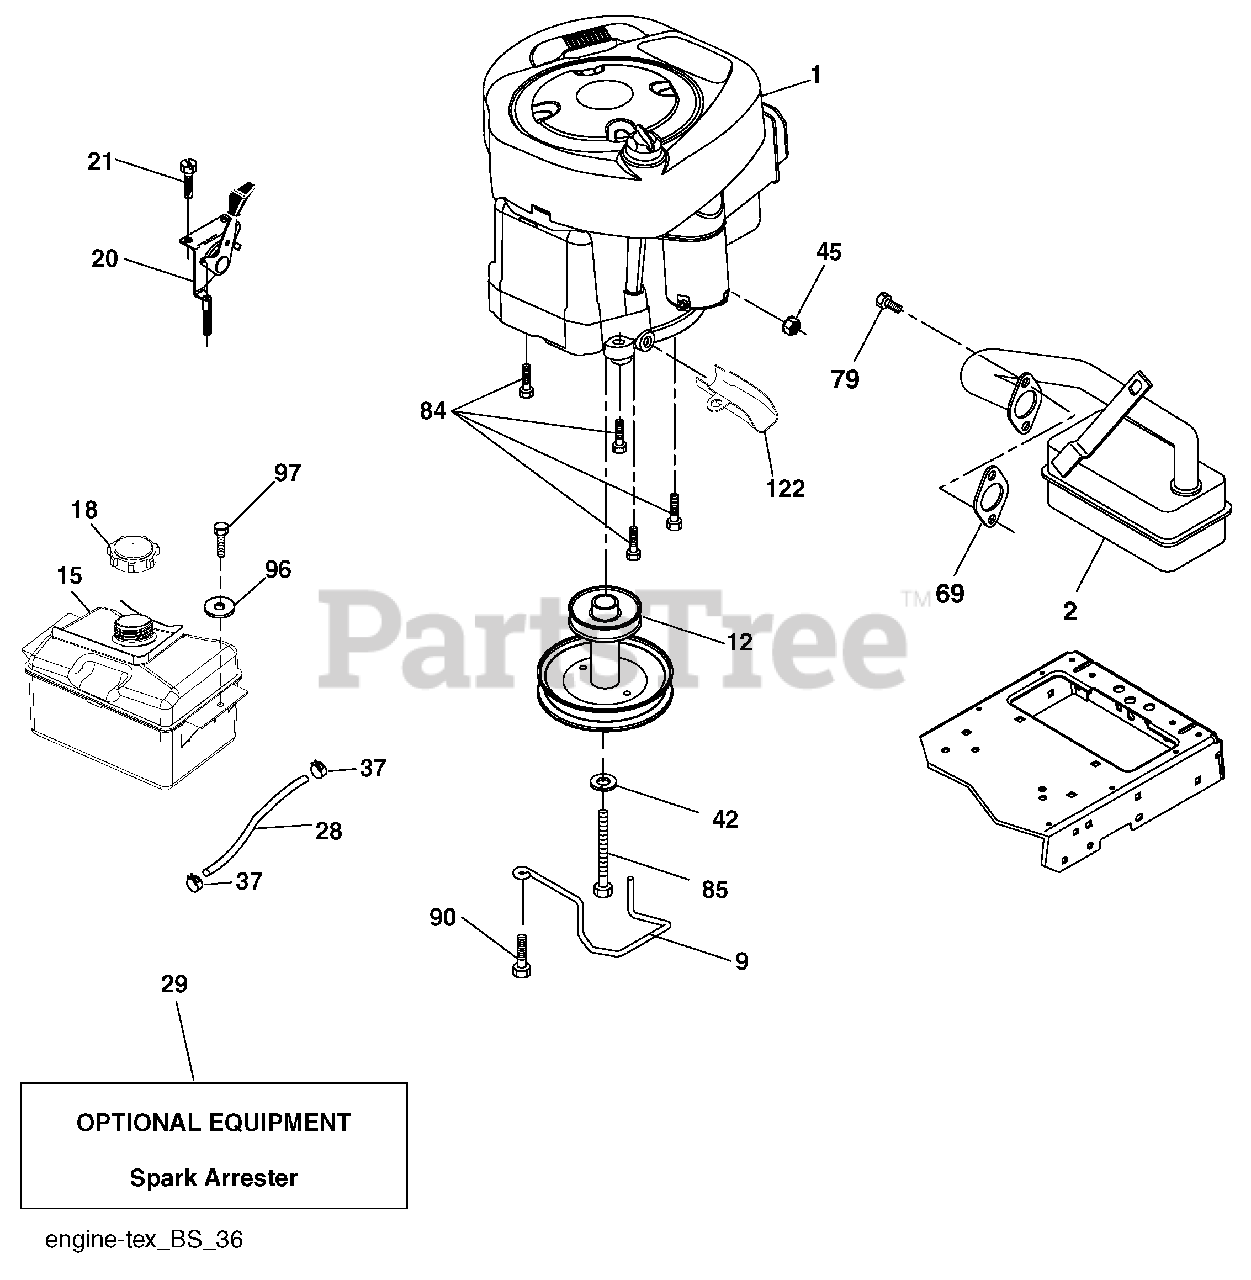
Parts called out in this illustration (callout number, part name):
9	Keeper Belt Engine
12	Pulley Engine
15	Tank Fuel
18	Cap Fuel
20	Control Throttle/Choke
21	Screw #10 x 0.750 BOS Thread
28	Fuel Line
29	Spark Arrester Kit
37	Clamp Hose
42	Washer Lock 7/16
45	Nut Keps Hex 1/4-20 unc
69	Gasket
79	Screw 5/16-18 x 3/4
84	Screw 3/8-16 x 1/4
85	Bolt Hex 7/16-20 x 4 Gr. 5
90	Screw 3/8-16 x 1
96	Washer 9/32 x 7/8 x 16 Ga.
97	Screw 1/4-20 x 3/4
122	Extension Drain Oil
